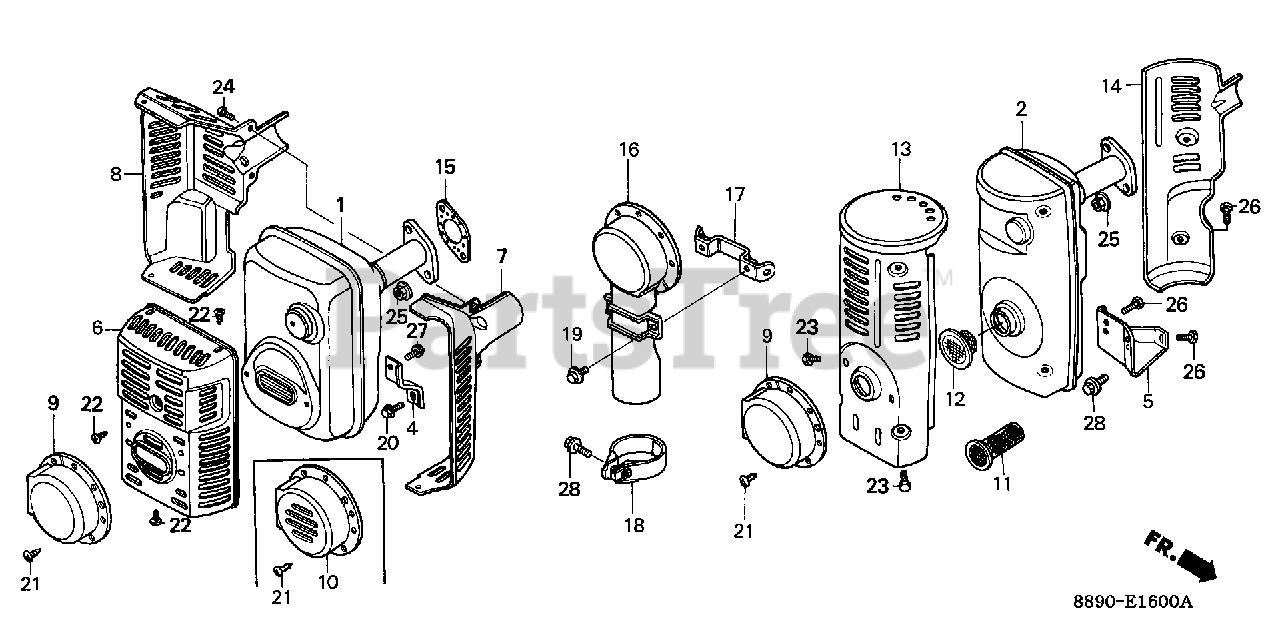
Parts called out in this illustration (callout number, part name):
2	MUFFLER
4	STAY, MUFFLER
5	STAY, MUFFLER
6	PROTECTOR, FR. MUFFLER (NOT AVAILABLE)
7	PROTECTOR, R. MUFFLER
8	PROTECTOR, L. MUFFLER
9	DEFLECTOR, MUFFLER
12	FLANGE, BAFFLE
13	PROTECTOR A, MUFFLER (NOT AVAILABLE)
14	PROTECTOR B, MUFFLER
15	GASKET, MUFFLER
20	BOLT, FLANGE (6X12) (CT200)
21	SCREW, TAPPING (4X8)
22	SCREW, TAPPING (4X8)
23	BOLT-WASHER (6X10) (NOT AVAILABLE)
23	BOLT, HEX. (6X8)
24	SCREW, PAN (4X6) (NOT AVAILABLE)
25	NUT, FLANGE (8MM)
26	BOLT, FLANGE (6X10)
27	BOLT, FLANGE (6X10)
28	BOLT, FLANGE (8X14)
28	BOLT, FLANGE (8X16)
